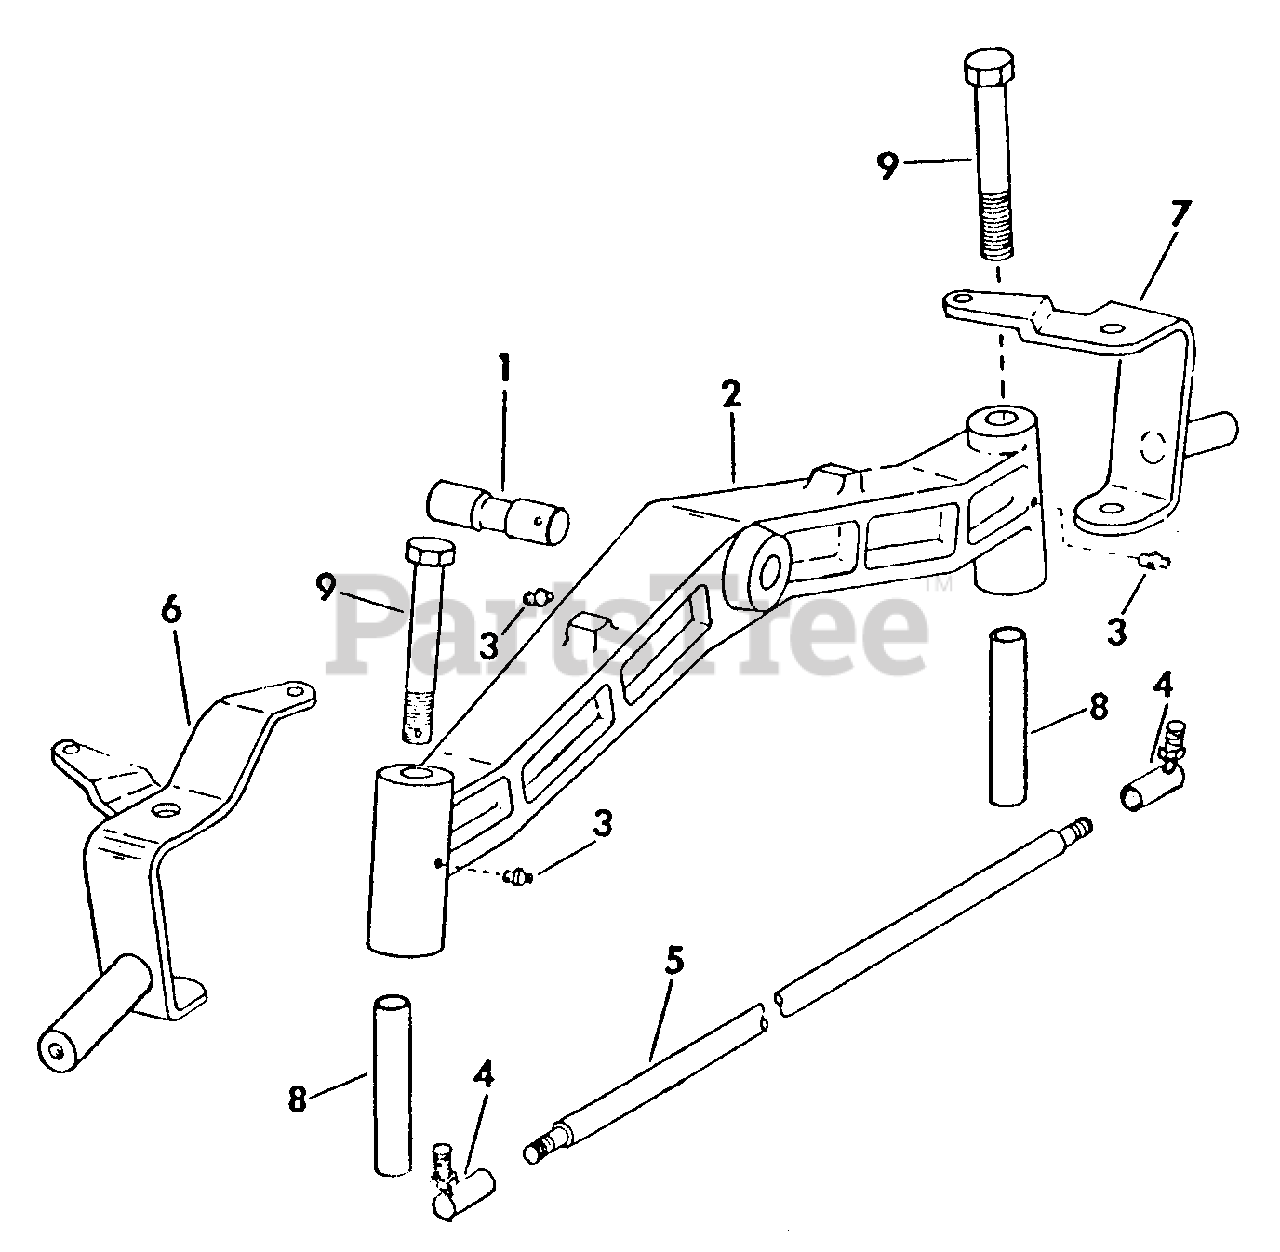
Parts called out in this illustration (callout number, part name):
1	Pin, Front Axle Pivot
4	Joint Assy, Ball
6	Knuckle Assy, Steering LH
7	Knuckle Assy, Steering RH
8	Spacer, Steering Knuckle
9	Bolt, Steering Knuckle
